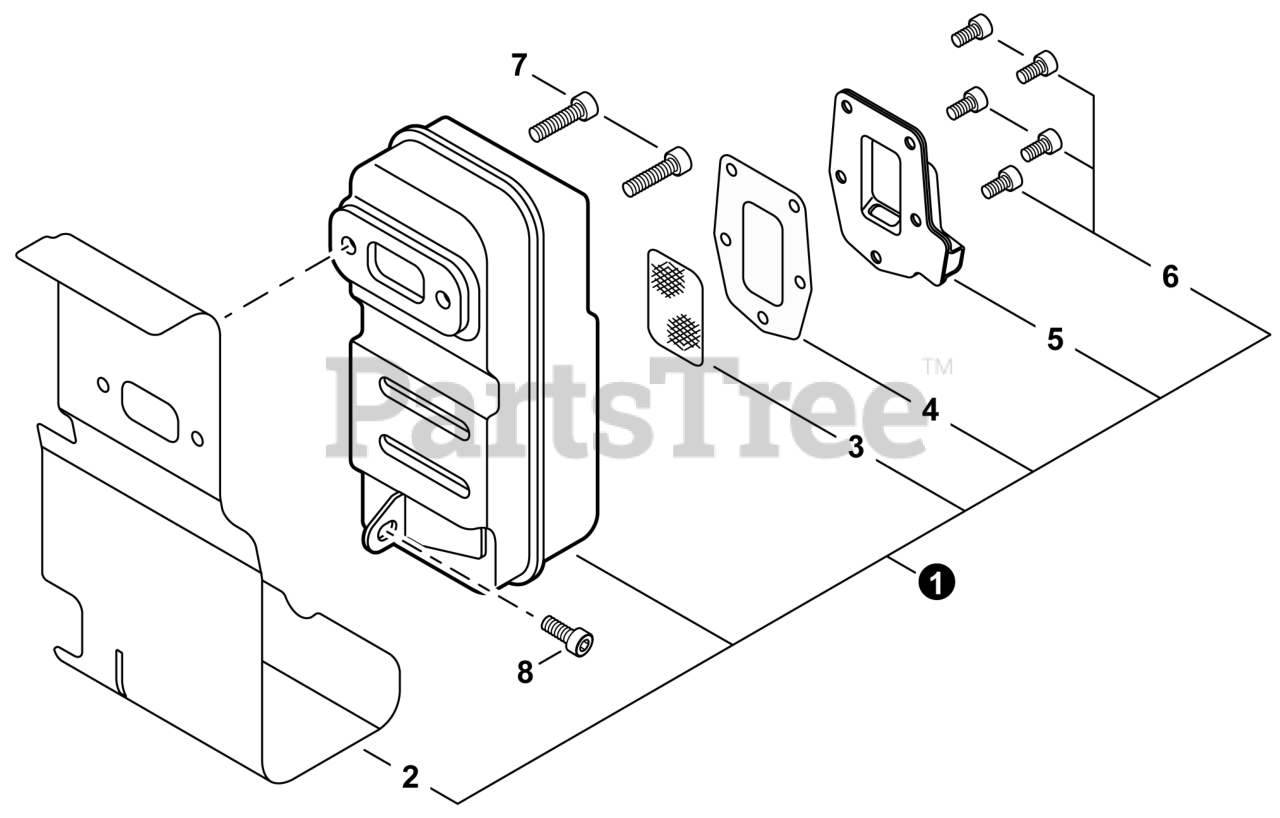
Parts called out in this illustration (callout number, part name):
1	MUFFLER ASSY
2	HEAT SHIELD, EXHAUST
3	SCREEN, SPARK ARRESTER
4	GASKET, EXHAUST
5	GUIDE, EXHAUST
6	BOLT, TORX 4×10
7	BOLT 6×20
8	BOLT, TORX 5×16
